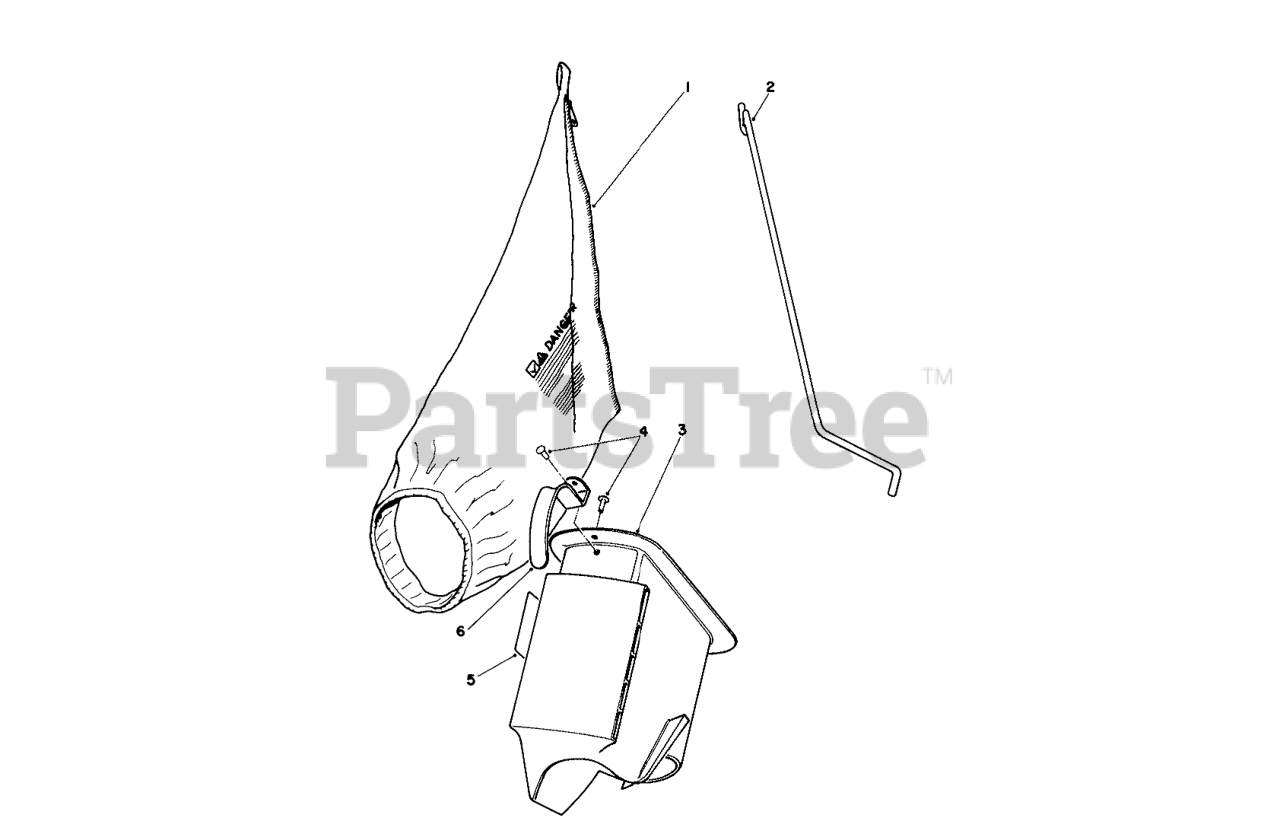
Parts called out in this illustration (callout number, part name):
1	BAG REPLACMNT44-0540
2	BAG ROD
3	Grass Chute (Incl. Ref. #4 & 6)
4	RIVET 3/16 X 7/16
5	BAG CHUTE DECAL
6	HANDLE-GRASS CHUTE
